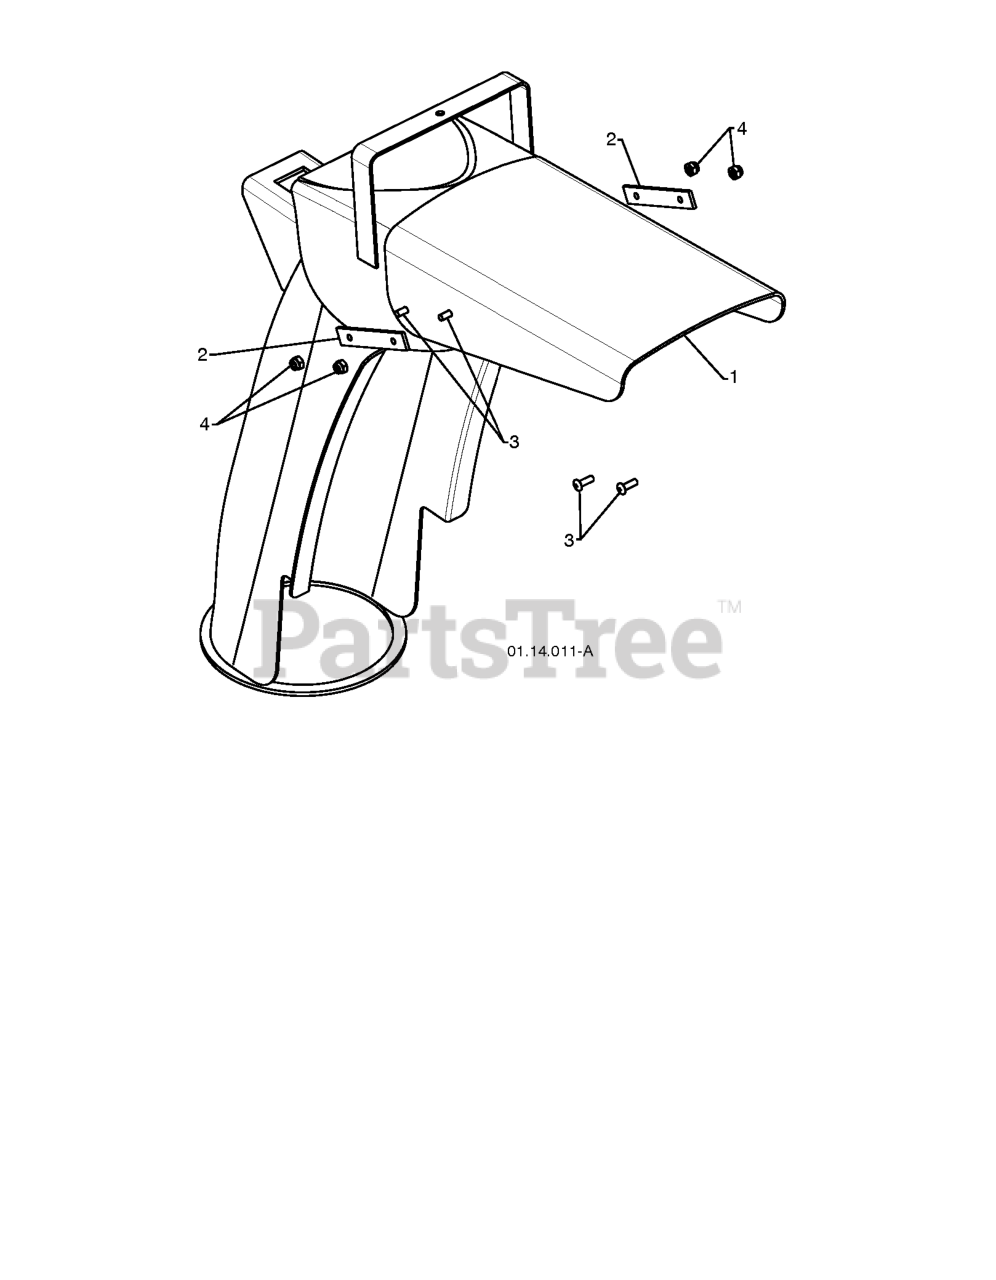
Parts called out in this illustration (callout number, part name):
1	SHIELD.DEFLECTOR.BLACK.SNOW
2	STRAP.DEFLECTOR.SHIELD
3	SCREW.#8.MACH
4	NUT.HEX.#8
